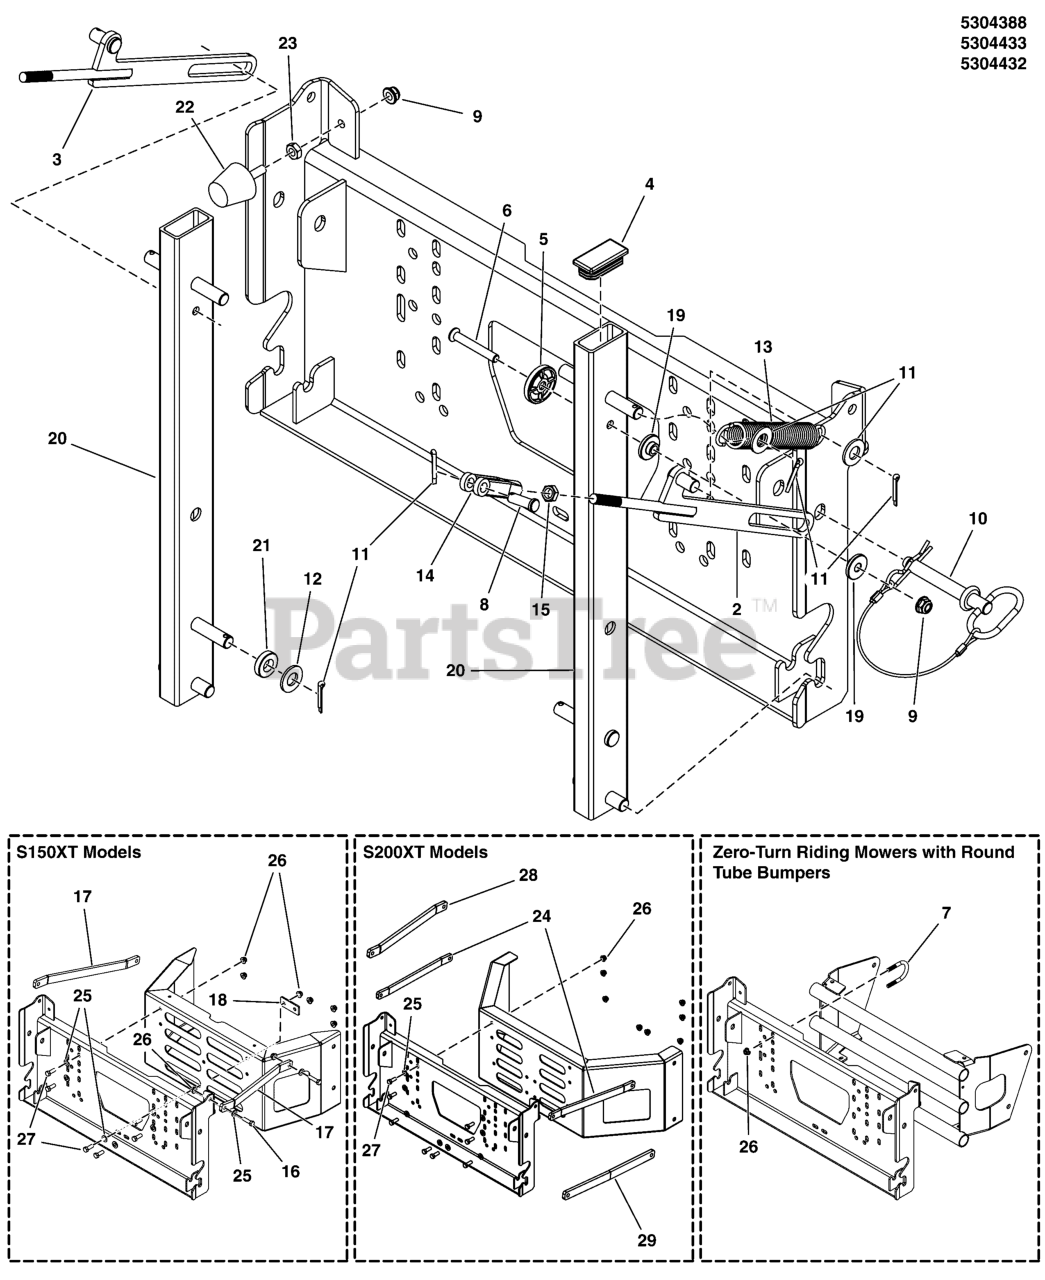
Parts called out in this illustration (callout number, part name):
1	WELD, HOPPER MOUNT, ZTR - BLK
2	WELD, RIGHT LATCH PULL, ZTR - BLK
3	WELD, LEFT LATCH PULL, ZTR - BLK
4	PLUG, 1 X 2, 10-14 GA. TUBING
5	SPACER, .34 X 1.54 X .25, PL
6	SCREW, 5/16-18X2.25, FLAT HEAD SOC, CZ
7	U-BOLT, 3/8 X 1-1/4
8	PIN, CLEVIS, 3/8 X 1-1/8, PLATED
9	NUT, 5/16-18 HEX NYLOCK FLANGE
10	PIN, HITCH, .50 X 3.25 W/ LAY
11	PIN, 3/32 X .750, COT, ZINC/CLEAR
12	WASHER, 1/2 SAE
13	SPRING, EXTENSION, 1.00
14	CLEVIS 3/8-24, PLASTIC
15	NUT, 3/8-24 HEX JAM
16	BOLT, 3/8-16 X 1-1/4" GD5 CZ
17	BAR, STAY STRAP, S150XT-52 - BLK
18	PLATE, BACKER, 150XT - BLK
19	SPACER,HYDRAULIC LIFT PIVOT
20	WELD, SUPPORT TUBE, HOPPER - BLK
21	SPACER, .52 X 1.00 X .25, CZ
22	BUMPER, RUBBER 5/16-18
23	NUT, 5/16-18 HEX JAM
24	BAR, STAY STRAP, S200XT-61 - BLK
25	WASHER, 3/8 SAE
26	NUT, 3/8-16 HEX NYLOCK FLANGE
27	BOLT, 3/8-16 X 1" GD5 CZ
28	BAR, LEFT STAY STRAP, S200XT, 12FT - BLK
29	BAR, RIGHT STAY STRAP, S200XT, 12FT, BLK
